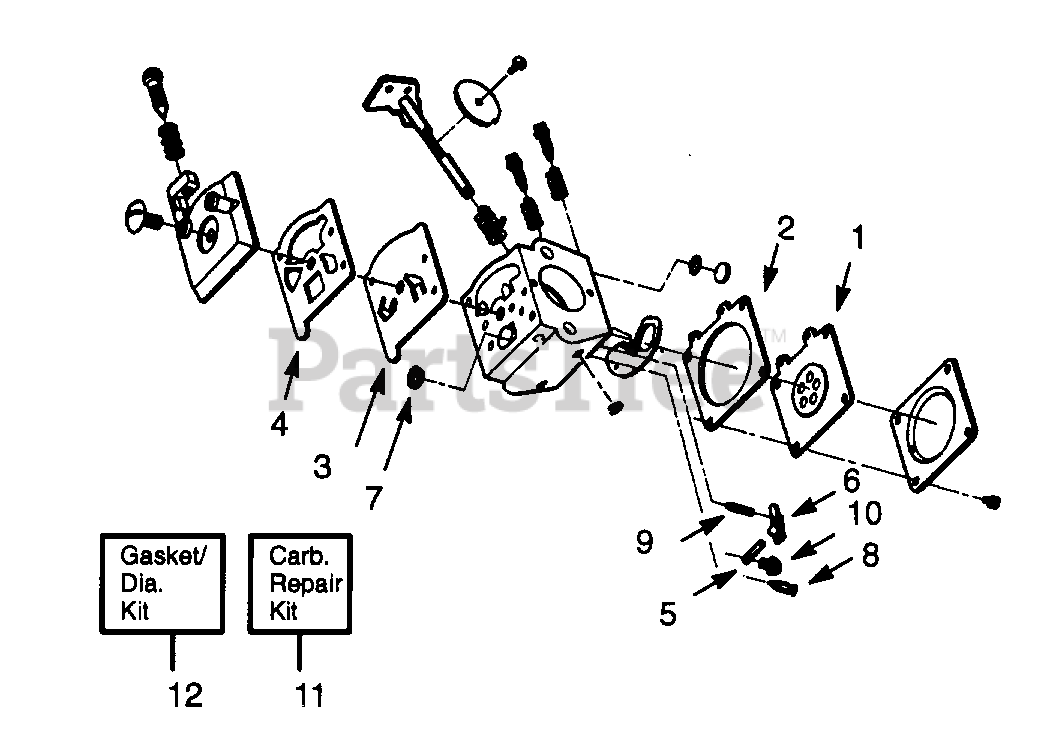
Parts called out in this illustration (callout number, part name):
1	Metering Diaphragm
2	Metering Diaphragm Gasket
3	Pump Gasket
4	Pump Diaphragm
5	Metering Lever Pin
6	Metering Lever
7	Inlet Screen
8	Inlet Needle Valve
9	Metering Lever Spring
10	Metering Lever Pin Screw
11	Carb. Kwik Repair Kit
12	Carb. Gasket/Diaphragm Kit
